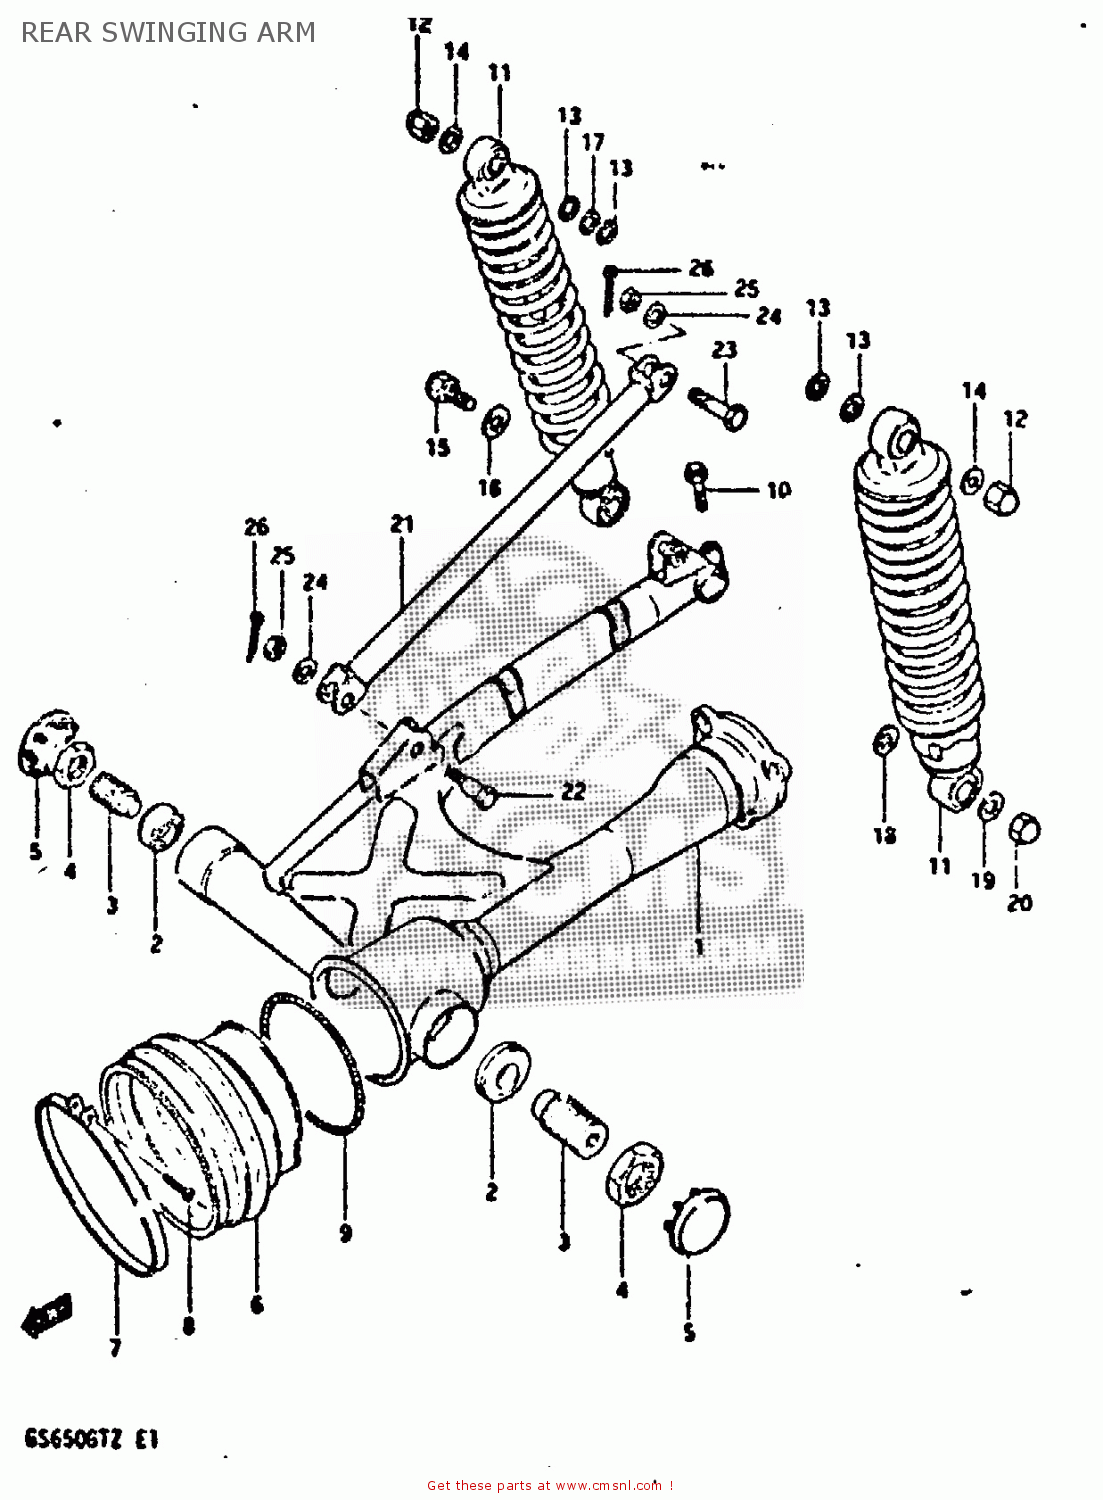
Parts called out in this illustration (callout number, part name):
1	SWING ARM ASSEMBLY,REAR
2	BEARING(15X35X11.75)
3	BOLT,REAR SWING ARM PIVOT
4	NUT (22MM)
5	CAP,REAR SWING ARM PIVOT
6	BOOT,PROPELLER SHAFT
7	CLAMP
8	SCREW 4X25
9	SPRING,PROPELLER SHAFT
10	BOLT
11	SHOCK ABSORBER, REAR
12	NUT
13	WASHER
14	WASHER
15	BOLT 12X33
16	WASHER (12.5X24X1.6)
17	WASHER (12.5X24X3.2)
18	WASHER
19	WASHER
20	NUT, LOWER LH
21	TORQUE LINK,REAR
22	BOLT
23	BOLT(10X39)
24	WASHER
25	NUT
26	PIN 20X20
